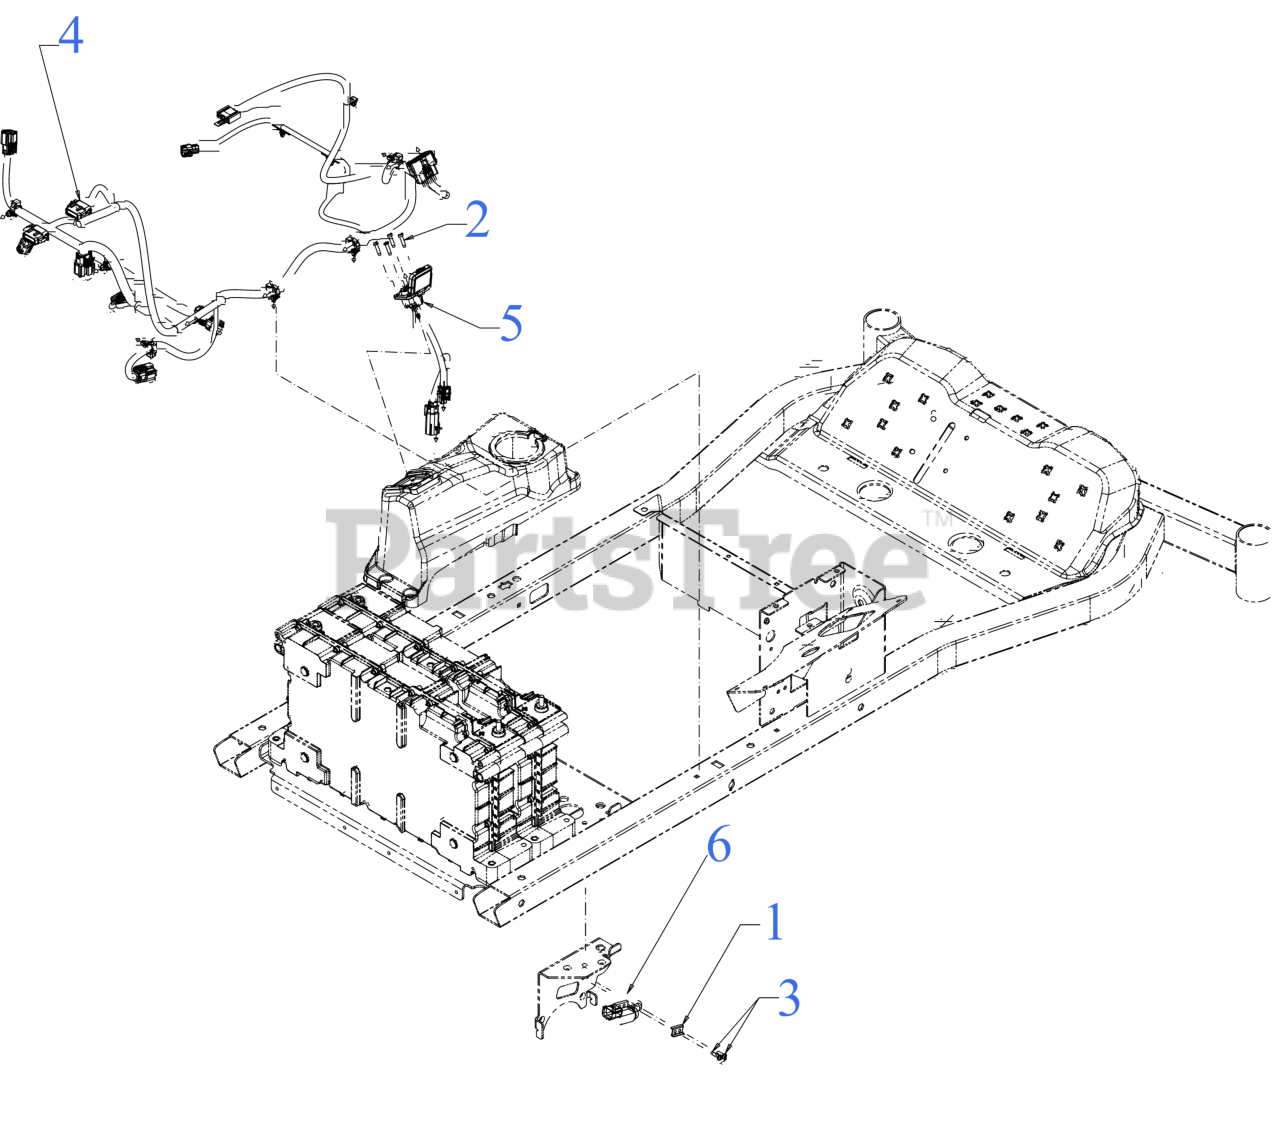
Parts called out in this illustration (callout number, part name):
1	PLATE-SWITCH
2	SCREW, #8-16X.750 PH
4	MAIN HARNESS (VCM PDM GEN2)
5	CHARGER PORT HARNESS (8-PIN)
6	SEALED PLUNGER SWITCH
